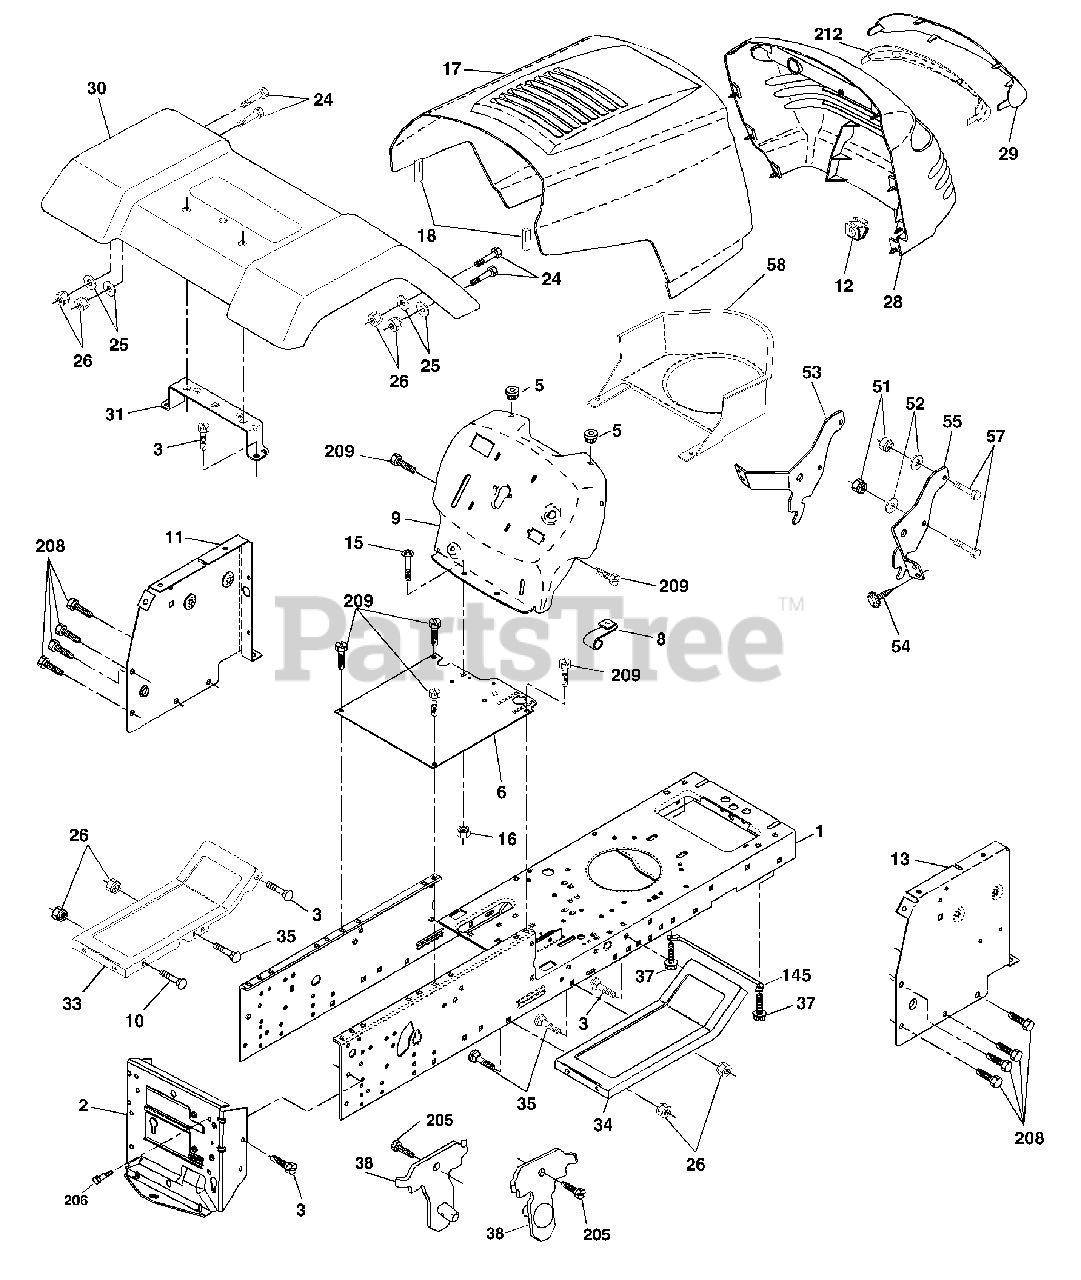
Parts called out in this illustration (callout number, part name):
1	Chassis
2	Drawbar
3	Screw 3/8-16 x 3/4
5	Bumper Hood/Dash
6	Saddle Slkscr Flt LT
8	Clip Retainer Slide-On
9	Dash
10	Bolt Rdhd Sqnk 3/8-16unc X 1
11	Panel Dash LH
12	Clip Tinnerman Grille P/L
13	Panel Slkscr Dash RH
15	Screw Mach TRHD 5/16-18 unc x 3/4
16	Nut Keps 5/16-18 Unc
17	Hood Asm
18	Bumper Hood
24	Bolt Fin Hex 3/8-16 unc x 1 Gr. 5
25	Washer 13/32 X 13/16 x 12 Ga
26	Nut Hex Lock W/Ins. 3/8-16 Unc
28	Grille/Lens Asm
29	Lens Headlight Bar Clear
31	Bracket Fender Repl 109873x
33	Footrest Pnt Lh
34	Footrest Pnt Rh
35	Bolt Rdhd Sht Sqnk 3/8-16 x 3/4
37	Screw Thdrol 5/16-18 x 1/2
38	Bracket Asm Pivot Mower Rear
51	Nut Lock Hex w/Ins 1/4-20
52	Washer 9/32 x 7/8 x 16 Ga.
53	Bracket, Grille LH
54	Screw
55	Bracket, Grille RH
57	Bolt Hex 1/4-20 x 3/4
58	Air Duct P/L
145	Rod Pivot Chassis/Hood
205	Screw Thdrol 3/8-16 x 1/2
206	Bolt Shoulder 5/16-18
208	Screw thdrol 3/8-16 x 1/2
209	Screw Hex Wsh Thdrol 3/8-16
212	Insert Lens Reflective
